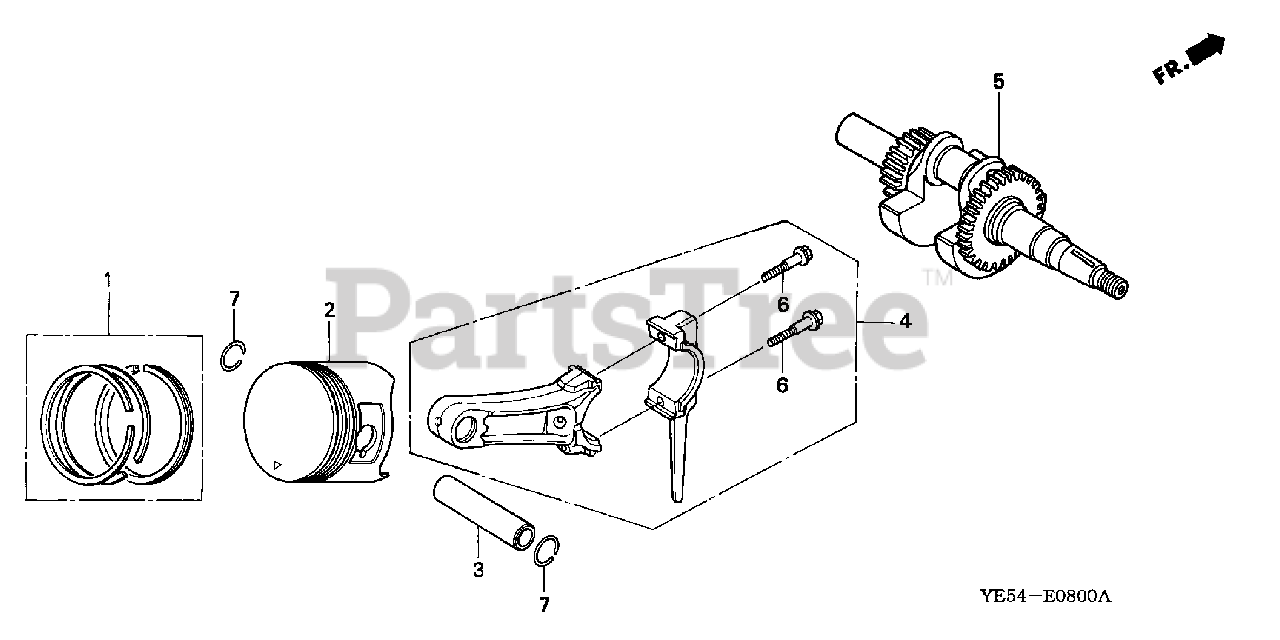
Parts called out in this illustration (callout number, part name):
1	RING SET, PISTON (STD)
1	RING SET, PISTON (STD) (TEIKOKU)
1	RING SET, PISTON (STD) (NIPPON)
1	RING SET, PISTON (OS 0.25) Use up to Engine SN 3284616.
1	RING SET, PISTON (OS 0.25) Use from Engine SN 3993726.
1	RING SET, PISTON (OS 0.25) Use from Engine SN 3284617 to 3993725.
1	RING SET, PISTON (OS 0.50) Use up to Engine SN 3284616.
1	RING SET, PISTON (OS 0.50) Use from Engine SN 3993726.
1	RING SET, PISTON (OS 0.50) Use from Engine SN 3284617 to 3993725.
1	RING SET, PISTON (0.75) Use up to Engine SN 3284616.
1	RING SET, PISTON (0.75) Use from Engine SN 3993726.
1	RING SET, PISTON (0.75) Use from Engine SN 3284617 to 3993725.
2	PISTON (STD)
2	PISTON (OS 0.25)
2	PISTON (OS 0.50)
2	PISTON (0.75)
3	PIN, PISTON
4	ROD ASSY., CONNECTING
5	CRANKSHAFT (W-TYPE)
6	BOLT, CONNECTING ROD
7	CLIP, PISTON PIN (13MM)
